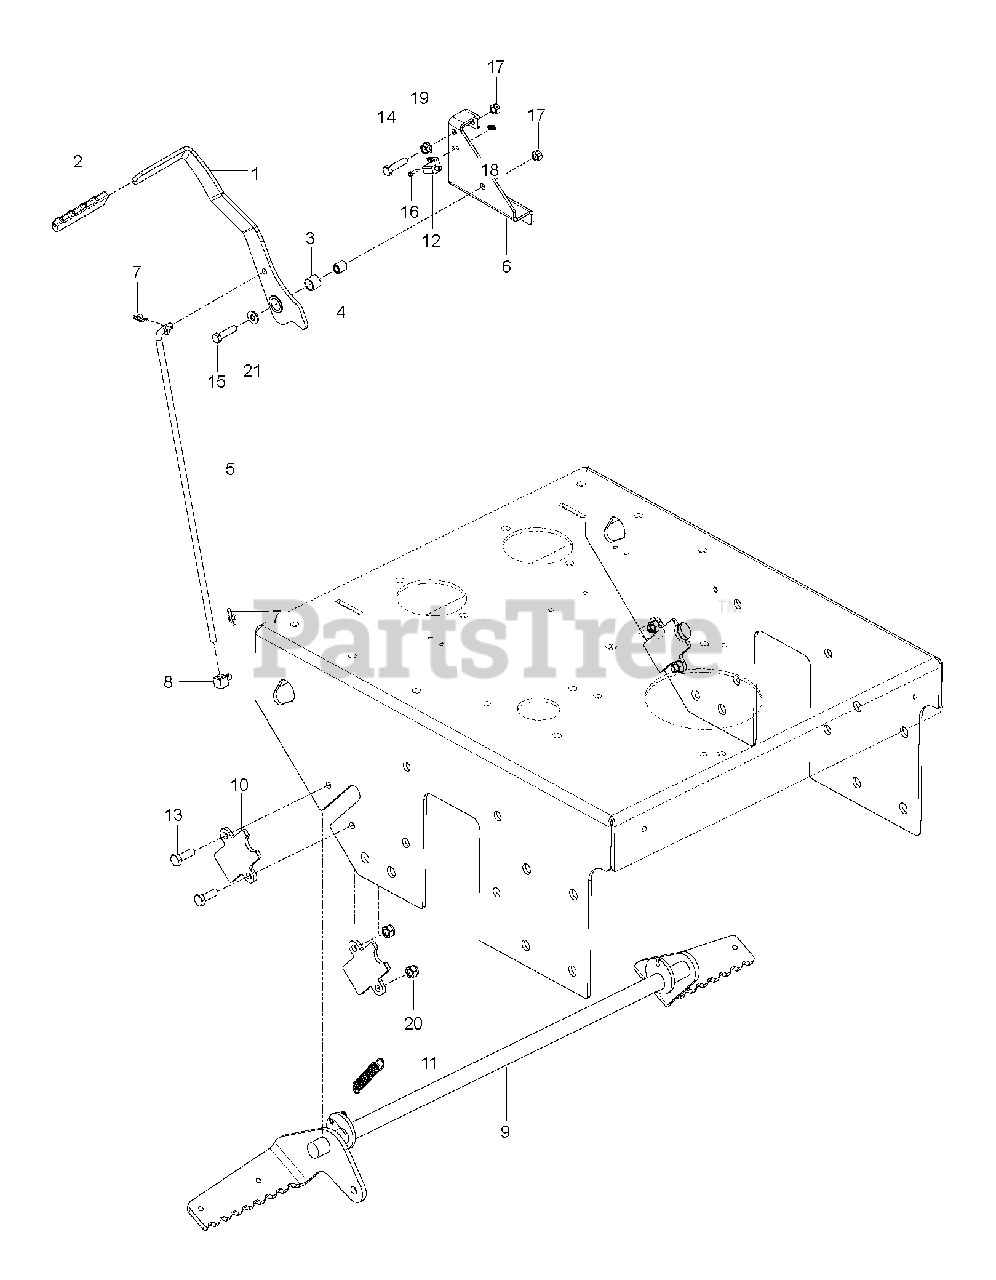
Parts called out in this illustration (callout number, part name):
1	LEVER PARK BRAKE LEVER WLDT 43
2	GRIP GRIP TCU19034
3	BUSHING PARK BRAKE LEVER BUSHI
4	SPACER PARK BRAKE LEVER SPACER
5	ROD DRIVE CONTROL FW 3858911
6	BRAKE BRAKE LOCATOR ARM WD 393
7	RING RUE .375 X .054 X 1.254 R
8	SWIVEL SWIVEL, 3/8-24
9	Brake Shaft
10	SHOE BRAKE SYSTEM FLOAT WALK 3
11	BRAKE SG-EXT WALK PARK BRAKE 8
12	SWITCH DOUBLE POLE N.O./N.O. 3
13	BOLT BOLT HEX .31-18 X 1.00 GR
14	BOLT BOLT HEX .38-16 X 1.00 GR
16	SCREW SCREW, MCH 10-24 X .75 H
17	NUT NUT, LK-CTR .38-16 YWZC
18	NUT NUT, 10-24 KEPS
19	NUT .375-16 WHIZ LOCK FLANGE
20	SERVICE PARTS SYSTEM NUT-LK-NY
21	WASHER WASHER, FL-STL .38 X .8
